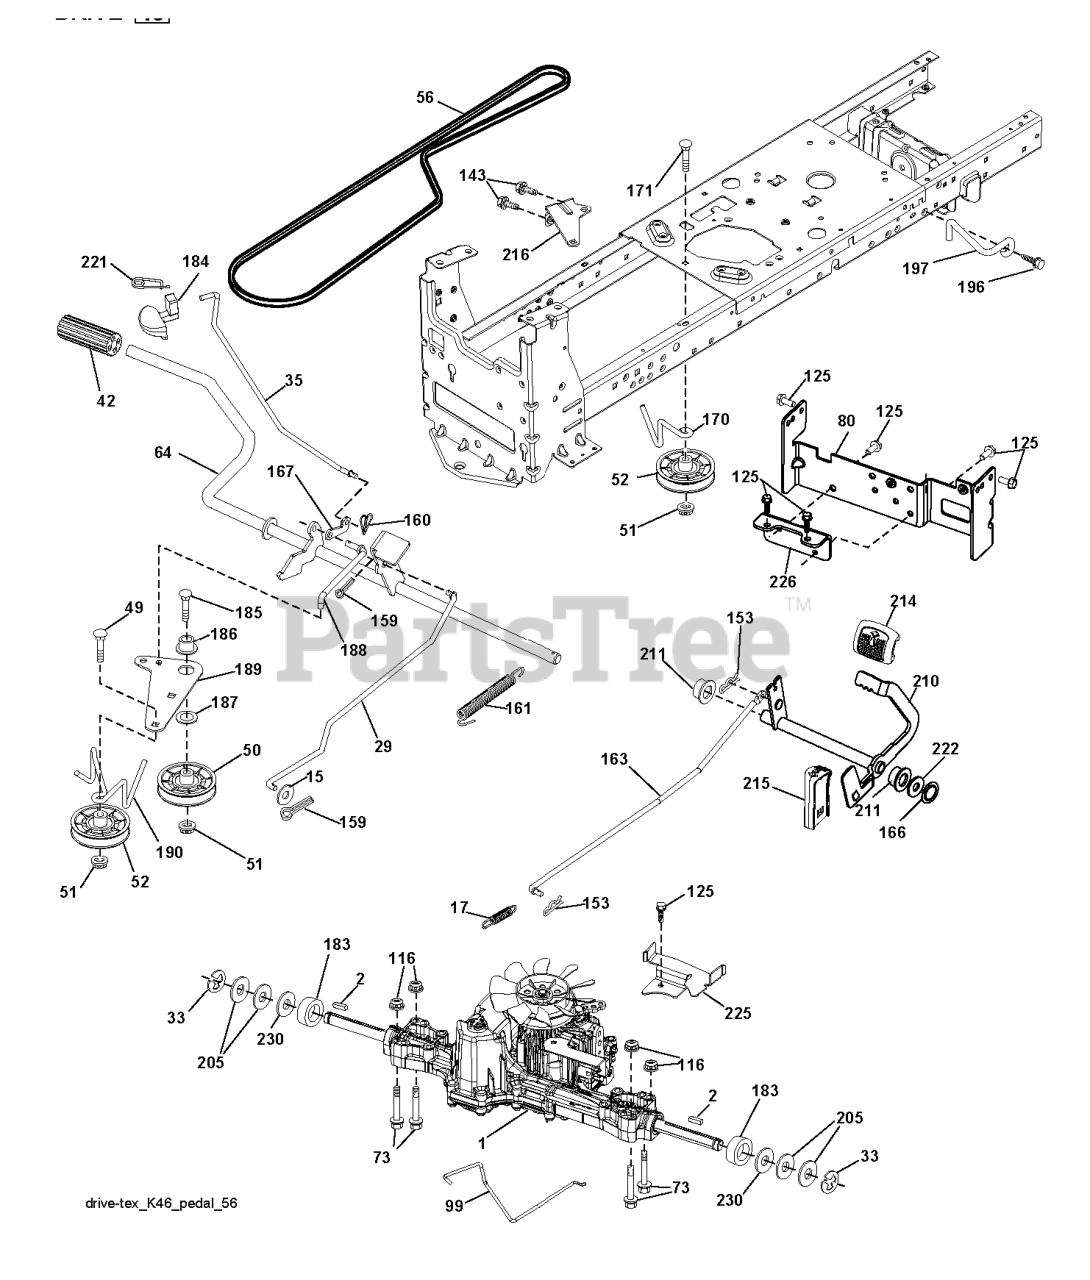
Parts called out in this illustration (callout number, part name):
2	SQUARE KEY
15	WASHER
17	SPRING.BRAKE.K46.GREEN
29	ROD.BRAKE.K46
35	ROD.CNTRL.PARK.PREDATOR.LT.TEX
42	PEDAL COVER T
50	IDLER.FLAT.910.OFFSET
51	NUT LOCK FLG 3/8-16 UNC
52	IDLER.V-GROOVE.910.OFFSET
56	V-BELT.MOWER.92.40.42/K46
64	SHAFT.ASM.PEDAL.BRK.CNTR
73	BOLT HEX 5/16-18 GR 5
80	STRAP TORQUE
99	ROD.SPRING.BYPASS.K46.LT.Z
116	NUT LOCK HEX FLANGE 5/16-18
125	SCREW
143	Screw 5/16-18 x 1/2 Hex, Self Tapping 5/16-18 x 1/2
153	RETAINER M
159	COTTER PIN
160	RETAINER CLIP
161	SPRING, RETURN LT
163	ROD.CONTROL.PEDAL.K46
166	NUT.PUSH.625.2006
167	LATCH.BRAKE.SPRING
170	KEEPER.V-IDLER.CENTER.
183	SPACER AXLE
184	HANDLE PARKING BRAKE
186	SPACER.RETAINER
187	WASHER 12/32X2X10GA
188	RP.LINK.CLUTCH.GROUND.DRIVE
189	BELLCRANK.GROUND.DRIVE.TEX.
190	KEEPER.BELLCRANK.DRIVE
196	SCREW 3/8-16X1
197	LINK.CLUTCH.ANIT-ROTAT
210	ROCKER.ASM.PEDAL.CONTR
211	BEARING.NYLON
214	PEDAL.FORWARD.PAD.TEX
215	PEDAL.REVERSE.TEX.GT.4
216	BRACKET.PULLEY.IDLER.W/TEX
221	RETAINER.SPRING.CLIP.H
222	WASHER 21/32 X 1-1/4 X 10 GA.
225	KEEPER.BELT.TRANSAXLE.K46
226	BRACKET.MOUNT.TORQUE.K46.TLT
230	WASHER.HARDENED
